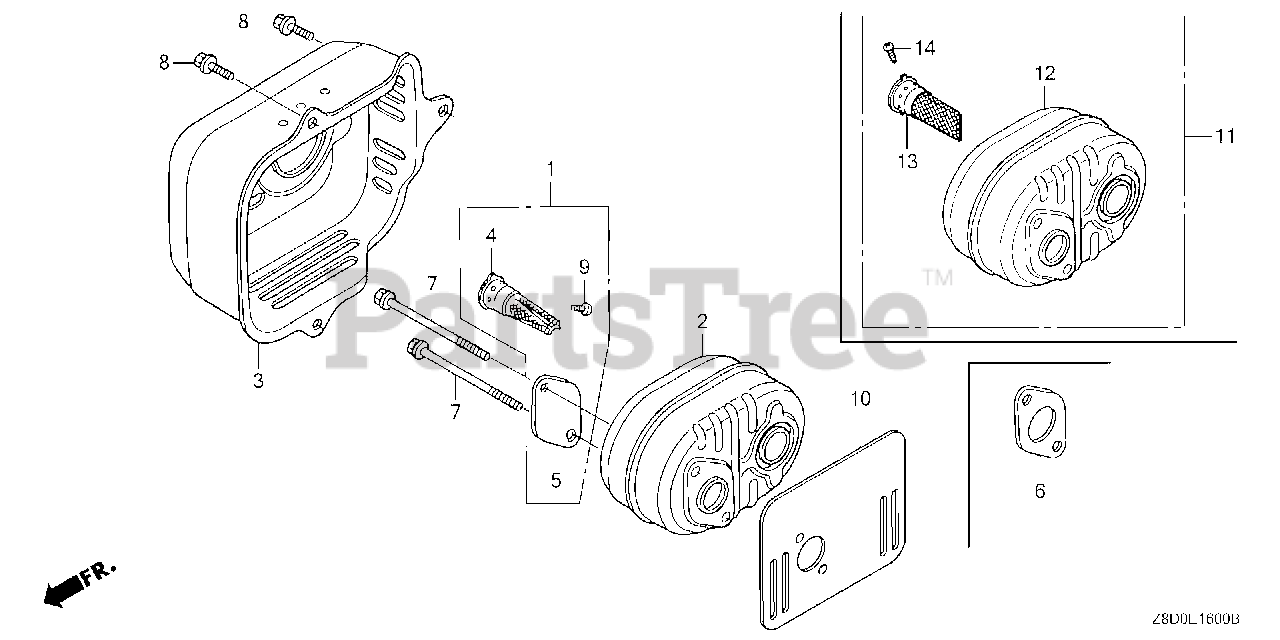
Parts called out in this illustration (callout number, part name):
1	ARRESTER KIT, SPARK
2	MUFFLER
3	PROTECTOR, MUFFLER
4	ARRESTER, SPARK (TO 1207644)
5	PLATE, ARRESTER NUMBER (TO INSTALL OPTIONAL SPARK ARRESTER)
6	GASKET, MUFFLER
7	BOLT, FLANGE (6X79) (CT200)
8	BOLT, FLANGE (6X12) (CT200)
9	SCREW, TAPPING (4X6) (TO INSTALL OPTIONAL SPARK ARRESTER)
11	MUFFLER ASSY. (ARRESTER)
12	MUFFLER
13	ARRESTER, SPARK
14	SCREW, TAPPING (4X6) (TO INSTALL OPTIONAL SPARK ARRESTER)
